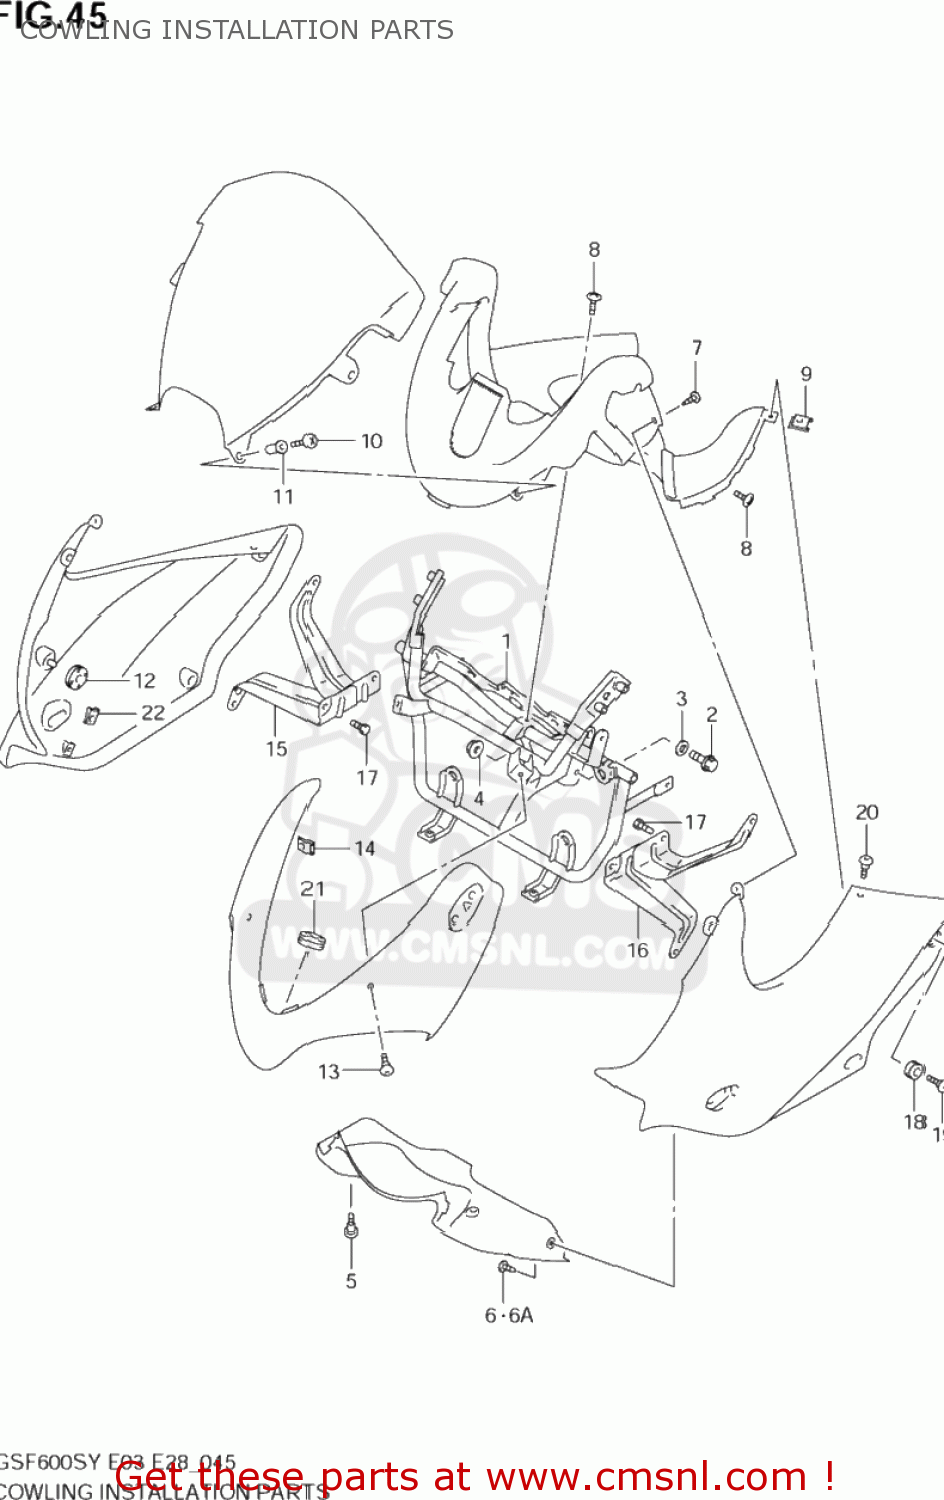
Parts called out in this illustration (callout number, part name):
1	BRACE COMP,COWLING
2	BOLT(8X33)
3	WASHER
4	NUT
5	SCREW(5X16)
6	SCREW
6A	CLIP(BLACK)
7	SCREW
8	SCREW 5X12
9	NUT,COWL
10	SCREW
11	NUT
12	CUSHION
13	SCREW(5X16)
14	NUT
15	BRACKET COMP,SIDE COWLING
16	BRACKET COMP,SIDE COWLING
17	BOLT
18	CUSHION
19	SCREW(6X20)
20	SCREW(5X16)
21	CUSHION
22	NUT
